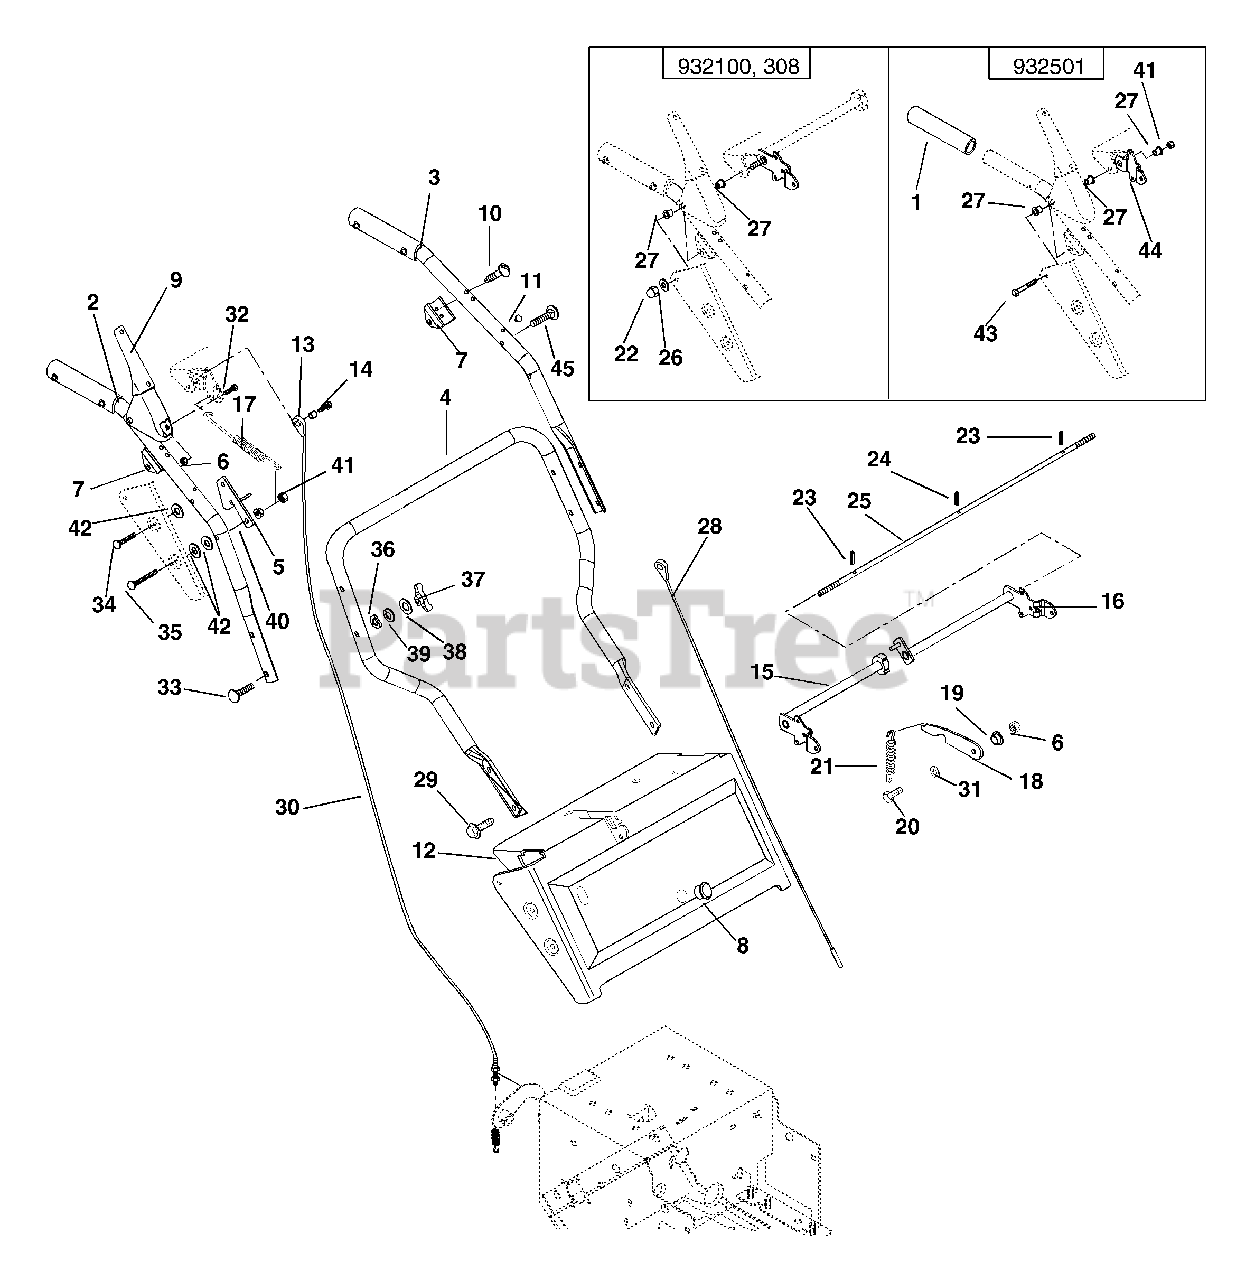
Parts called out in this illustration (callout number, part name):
1	HANDLE GRIP
2	HANDLEBAR, UPPER-RH
3	HANDLEBAR, UPPER-LH
4	HANDLEBAR, LOWER
5	@NUT-SPNLK-FLG .312-18 YWZC
6	@NUT-LK-CTR .25-20 YWZC
7	HANDLE PIVOT
8	SNAP BUSHING
9	CLUTCH LEVER - COATED
10	SCR-TAP 12-24X1.50 CROVH YZ BT
12	PANEL W/DECAL - 824
12	PANEL W/DECAL - 724
13	SPACER .230X.310X.255
14	@SCR-TAP 12-24X.50 HWH TR YWZC
15	INTERLOCK, RH
16	INTERLOCK, LH
17	SG-TENS .051X.50X5.12 WLD 10.4
18	ARM, LATCH
19	BSHG-FLG .265X.437X.329X1.00
20	@BLT-HEX .25-20X.75 GR5 YWZC
21	SG-TENS .048X.44X1.75 WLD 9
22	NUT-CROWN .312-18 YWZC
23	PIN-ROLL .156X.75
24	PIN-ROLL .125X1.00
25	ROD
26	WSHR-FL-STL .323X.625X.062 YWZ
27	BSHG-FLG .325X.465X.333X.685
28	CABLE, TRACTION CLUTCH
29	BLT SERHFWH .31-18X.62 GR5YWZC
30	CABLE, BLOWER CLUTCH
31	WSHR-FL-STL .281X1.000X.063
32	@BLT-HEX .25-20X.50 GR5 YWZC
33	@BLT-RDHDSQNK .31-18X2.25 G5YZ
34	@BLT-RDHDSQNK .31-18X1.75 G5YZ
35	BLT-RDHDSQSHNK.31-18X2.75G2YWZ
36	WASHER,SADDLE-.320 X.937 X.062
37	KNOB - WING .312-18 UNC
38	WSHR-FL-STL .328X.875X.062YWZC
39	WSHR-LK .312X.097 HVY YWZC
40	UPPER CABLE ANCHOR R H
41	@NUT-LK-CTR .31-18 YWZC
42	WSHR-FL-STL .505X.880X.072 YWZ
43	@BLT-HEX .31-18X2.50 GR5 YWZC
44	ARM
45	@BLT-RDHDSQNK .31-18X1.50 G5YZ
